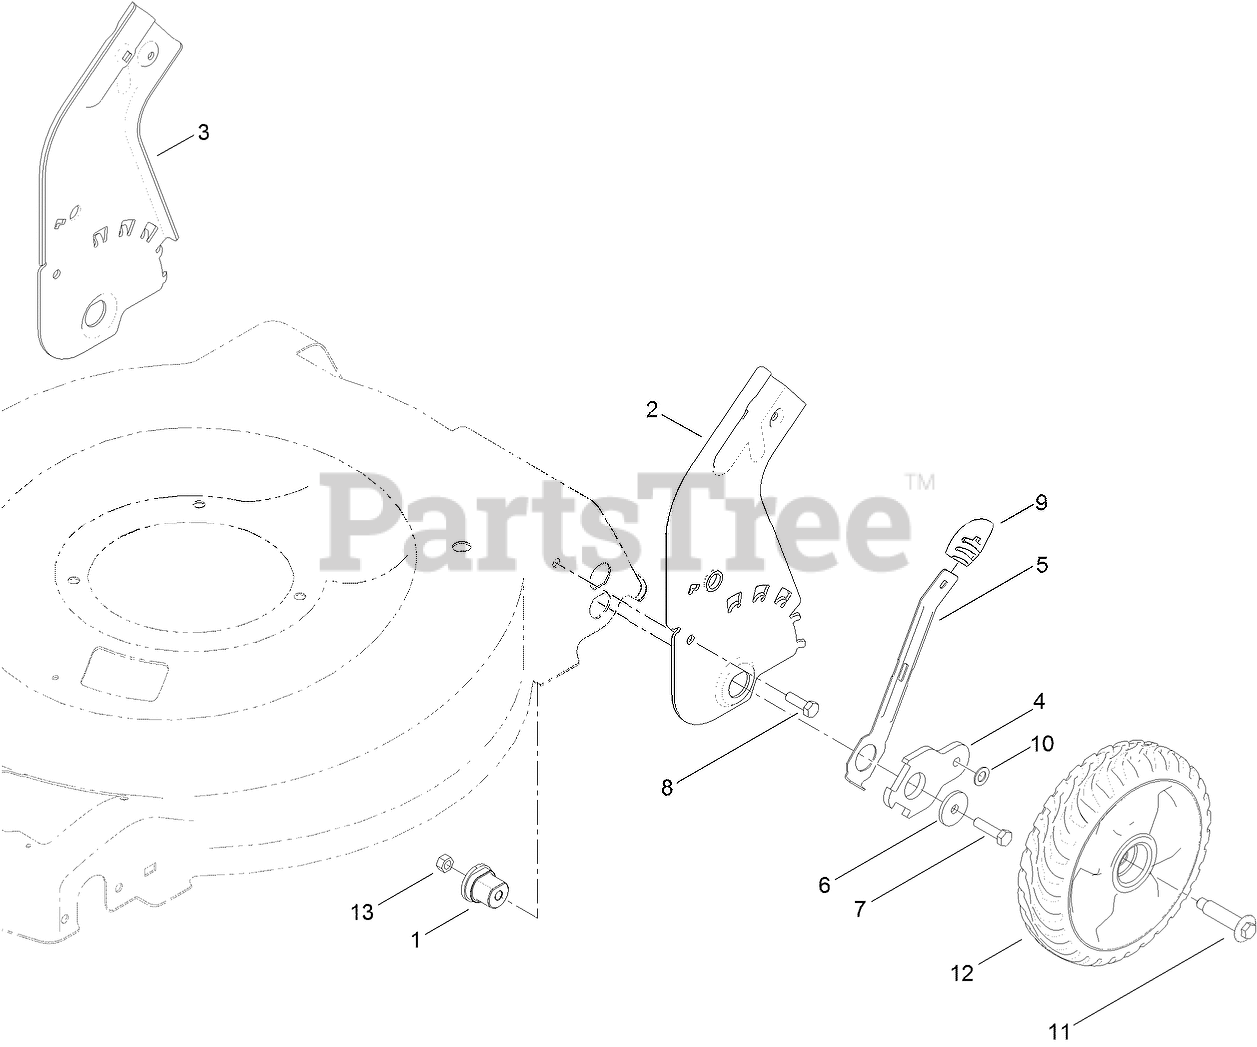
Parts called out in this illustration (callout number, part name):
1	BUSHING-MOUNT, HOC
2	PLATE-HOC, REAR (LH)
3	PLATE-HOC, REAR (RH)
4	ARM-PIVOT, REAR
5	ARM-SPRING, REAR
6	Washer-Flat
7	SCREW-HH
8	SCREW-HH
9	Knob-Lever, HOC
10	WASHER
11	BOLT-SHOULDER
12	8 INCH WHEEL ASM
13	NUT-LOCK, NI
